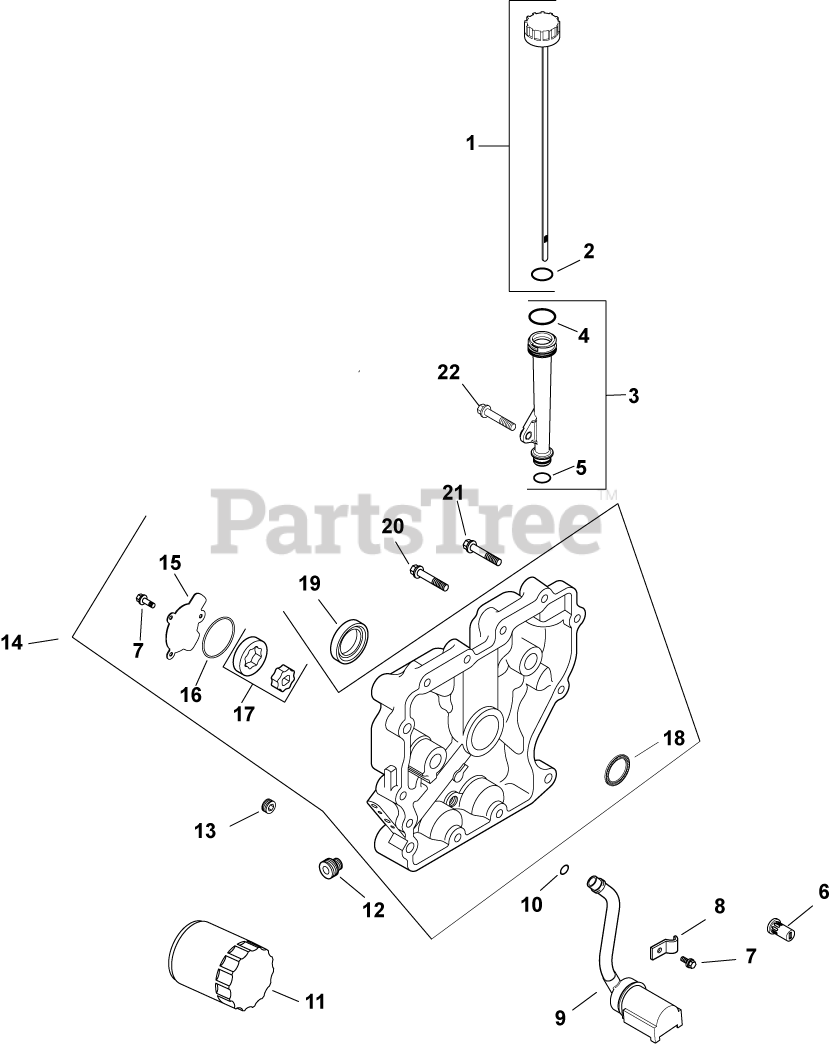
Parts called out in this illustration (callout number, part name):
1	KIT, OIL FILL CAP ASSEMBLY
2	O-RING, UPPER OIL FILL TUBE
3	KIT, OIL FILL TUBE - USE 12 755 113-S
4	O-RING, UPPER OIL FILL TUBE
6	VALVE, OIL PRESSURE RELIEF
7	SCREW,FLG THD FRM M5X0.8X16-(#25086398S)
9	KIT, OIL PICK-UP
10	O-RING (.5" DIA)
11	OIL FILTER
12	NIPPLE, OIL FILTER
13	PLUG, CTSK PIPE 1/8"
14	PLATE, CLOSURE & BEARING
15	COVER, OIL PUMP
16	O-RING (1.78" DIA)
17	PUMP ASSEMBLY, OIL
18	BEARING, CRANKSHAFT
19	SEAL, OIL
20	SCREW, FLG M8X1.25X45
21	SCREW, HEX FLANGE -USE 24 086 17-S
22	SCREW, FLG M8X1.25X50
